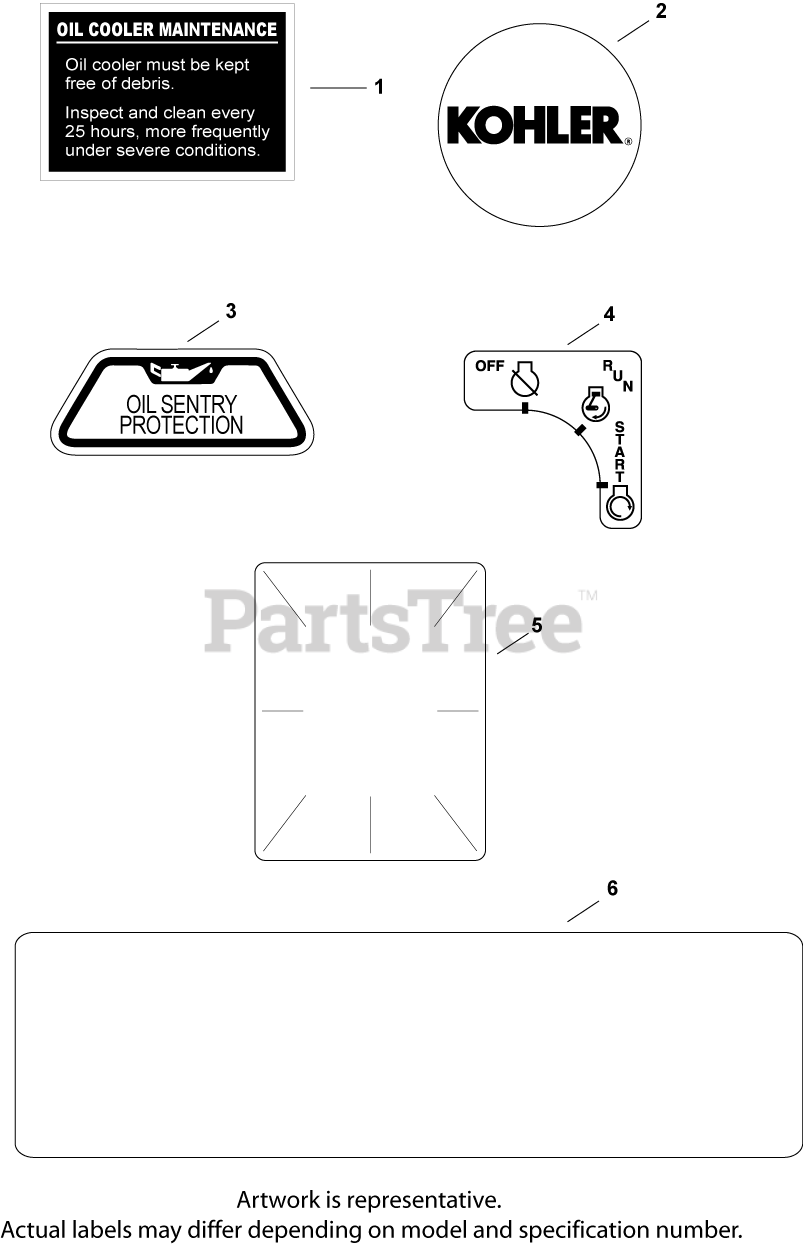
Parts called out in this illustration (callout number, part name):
1	DECAL, OIL COOLER - (#DSC)
2	LABEL, (ROUND KOHLER GOLD)-USE 24 113 18
3	DECAL, OIL SENTRY - (#DSC)
4	DECAL, KEY SWITCH
5	DECAL, CLEAR LAMINATE USE 25 113 70-S
6	DECAL, 22 HP
